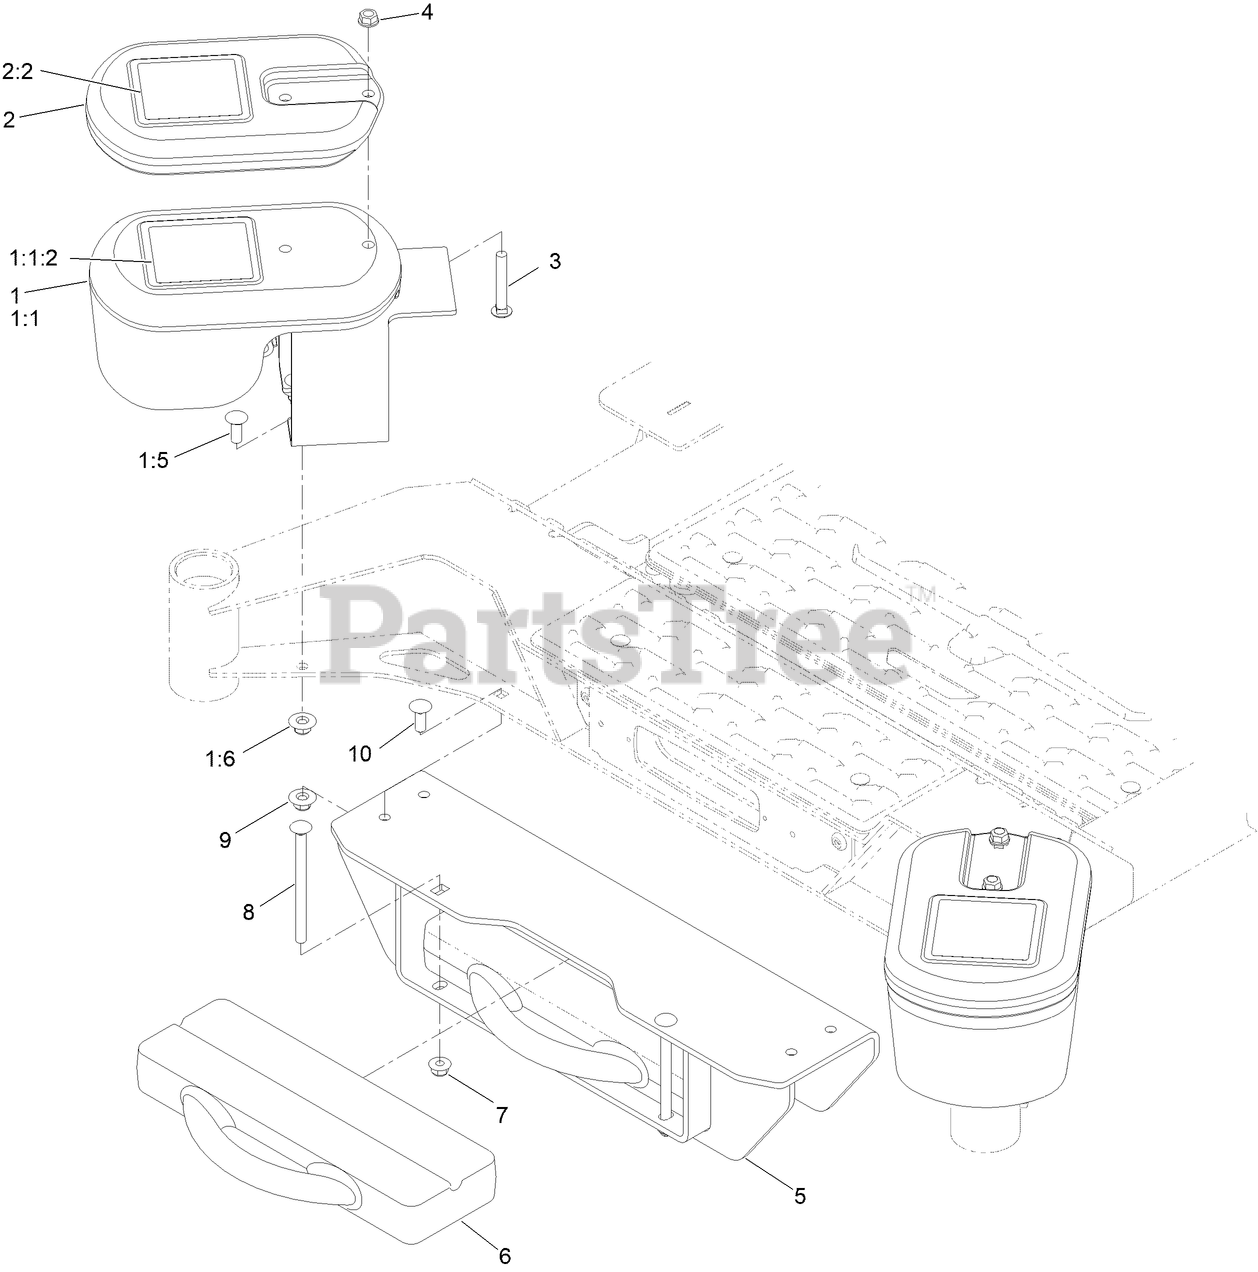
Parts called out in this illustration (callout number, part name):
1	ASM-CASTER WEIGHT
1:1	WEIGHT WITH DECAL ASM
1:1:2	DECAL-WARNING, TRACTION
1:5	SCREW-CARR
1:6	NUT-FLANGE, NI
2	WEIGHT
2:2	DECAL-WARNING, TRACTION
3	SCREW-CARR
4	NUT-HHF, WHIZ
5	WEIGHT BRACKET ASM
7	NUT-HF, NI
8	BOLT-CARR
9	NUT-FLANGE, NI
10	SCREW-CARR
